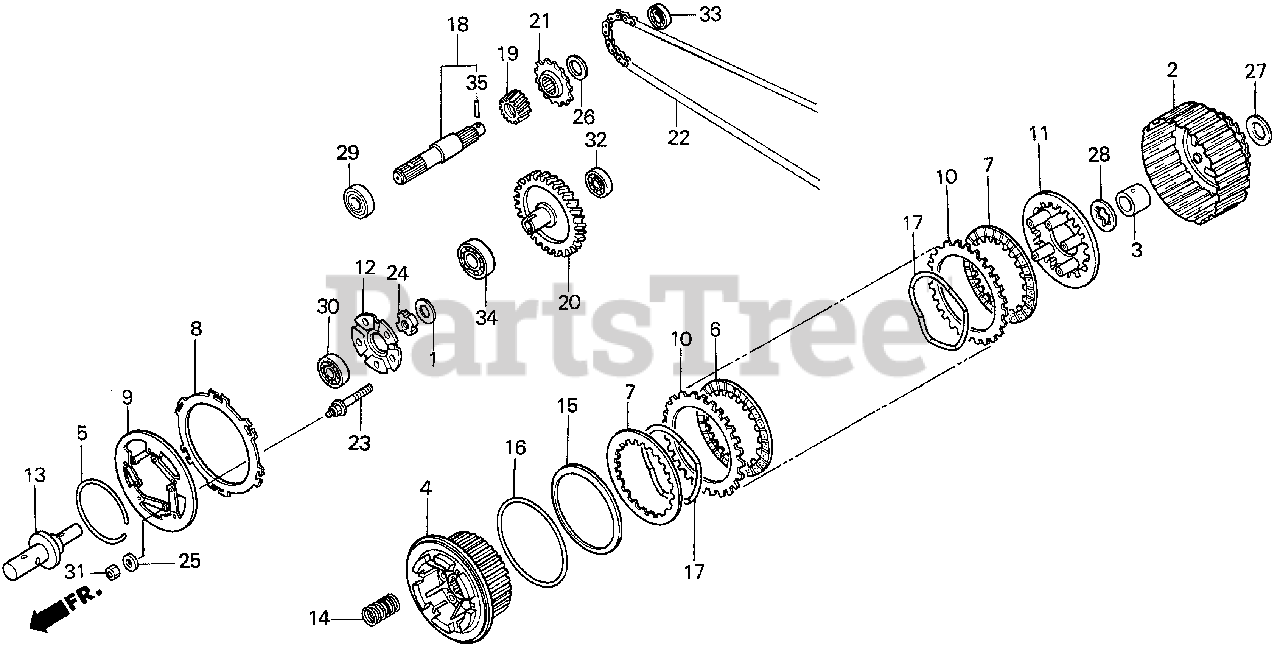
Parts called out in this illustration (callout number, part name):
1	WASHER, OIL FILTER ROTOR LOCKING
2	CLUTCH (OUTER)
3	GUIDE, CLUTCH (OUTER)
4	CENTER, CLUTCH
5	SET-RING (100.5MM)
6	DISK A, CLUTCH FRICTION
7	DISK B, CLUTCH FRICTION
8	PLATE B, BRAKE
9	PLATE C, BRAKE
10	PLATE, CLUTCH
11	PLATE, CLUTCH PRESSURE
12	PLATE, CLUTCH LIFTER
13	ROD, CLUTCH LIFTER
14	SPRING, CLUTCH
15	SPRING, CONED DISK
16	SEAT, SPRING
17	SPRING, CLUTCH SUPPORT
18	SHAFT, INPUT
19	GEAR, PUMP REDUCTION DRIVE
20	GEAR, PUMP REDUCTION DRIVEN
21	SPROCKET, DRIVE
22	CHAIN, PRIMARY DRIVE (240MBK-40) (DAIDO)
23	BOLT, SPECIAL (6X22)
24	NUT, LOCK (16MM)
25	WASHER (10MM)
26	WASHER, THRUST (17.2MM)
27	WASHER, THRUST (20MM)
28	WASHER B, SPLINE (20MM)
29	BEARING, RADIAL BALL U (60/20)
30	BEARING, RADIAL BALL (16003)
31	NUT, HEX. (5MM)
32	BEARING, RADIAL BALL (6202)
33	BEARING, RADIAL BALL (6003U)
34	BEARING, RADIAL BALL (6204U)
35	ROLLER (3X16.8)
